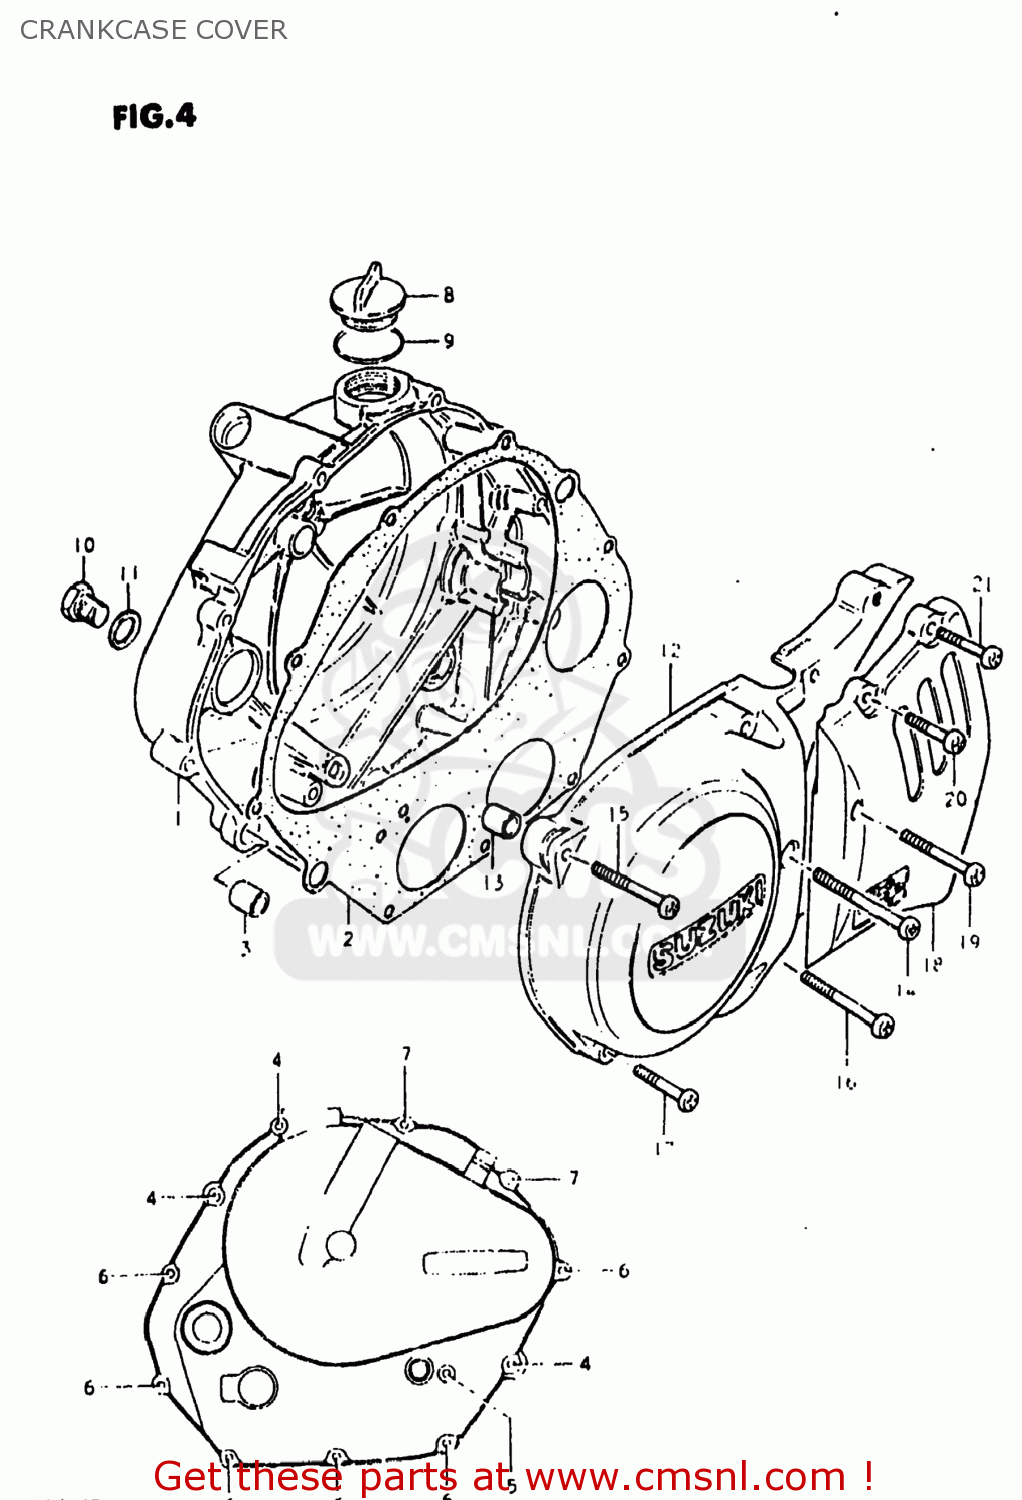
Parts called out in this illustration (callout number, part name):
1	COVER,CLUTCH
2	GASKET,CLUTCH COVER (MCA)
3	PIN
4	SCREW
5	SCREW
6	SCREW (6X35)
7	SCREW
8	CAP
9	O RING(D:2.2,ID:32)
10	PLUG (14X12)
11	GASKET(14X19.2X2) (NAS)
12	COVER
13	PIN
14	SCREW 6X60
15	SCREW
16	SCREW (6X45)
17	SCREW (6X35)
18	COVER,SPROCKET
19	SCREW
20	SCREW
21	SCREW
